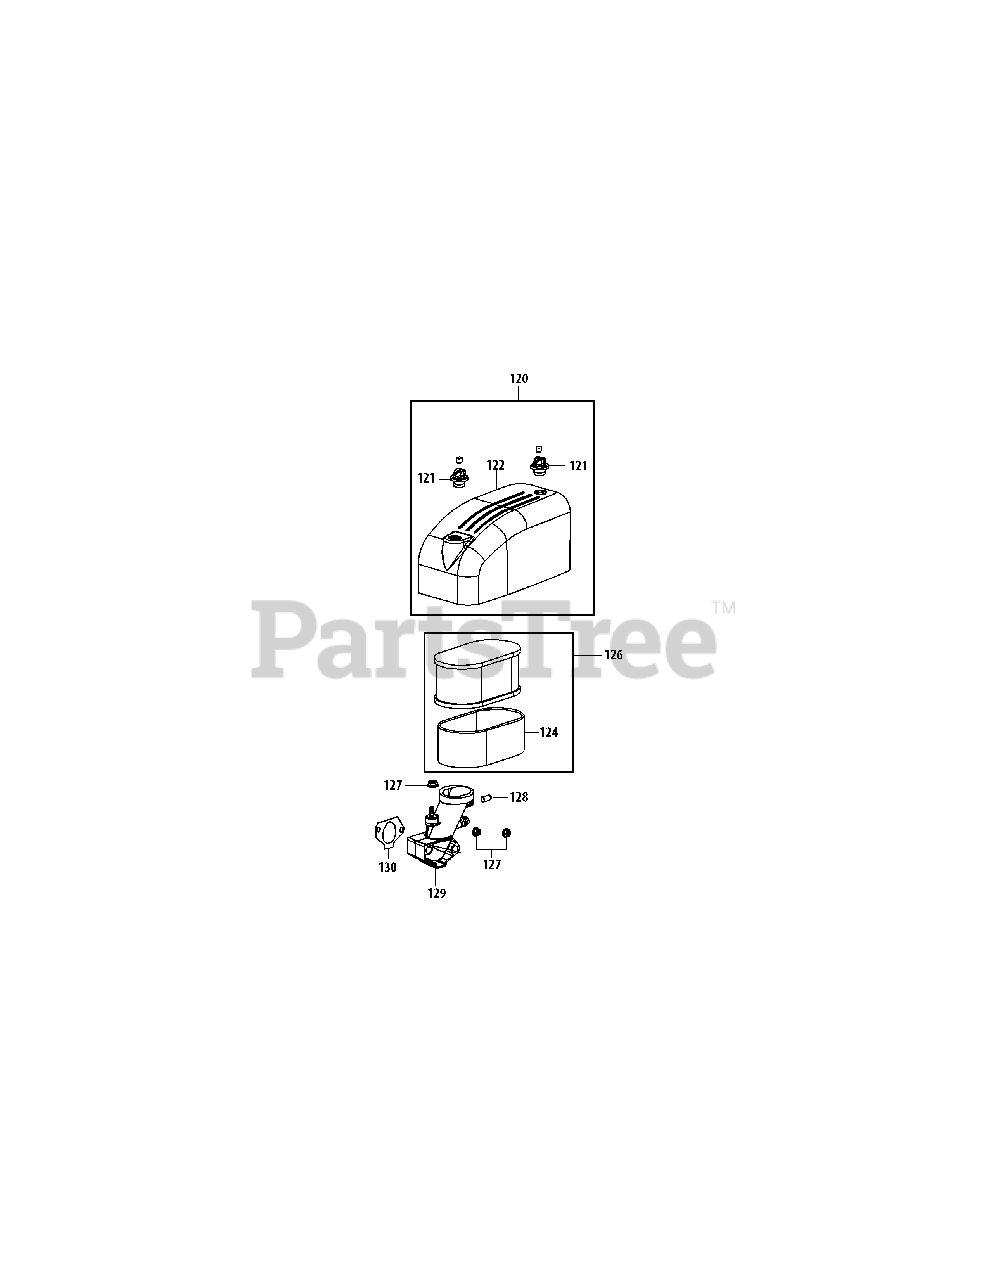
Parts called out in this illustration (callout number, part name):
120	Air Filter Cover Assembly
121	Air Filter Lock Nut
122	Air Filter Cover
124	Sponge Filter
126	Air Filter Assembly
127	Nut M6
128	Rubber Cap
129	Intake Manifold
130	Manifold Gasket
